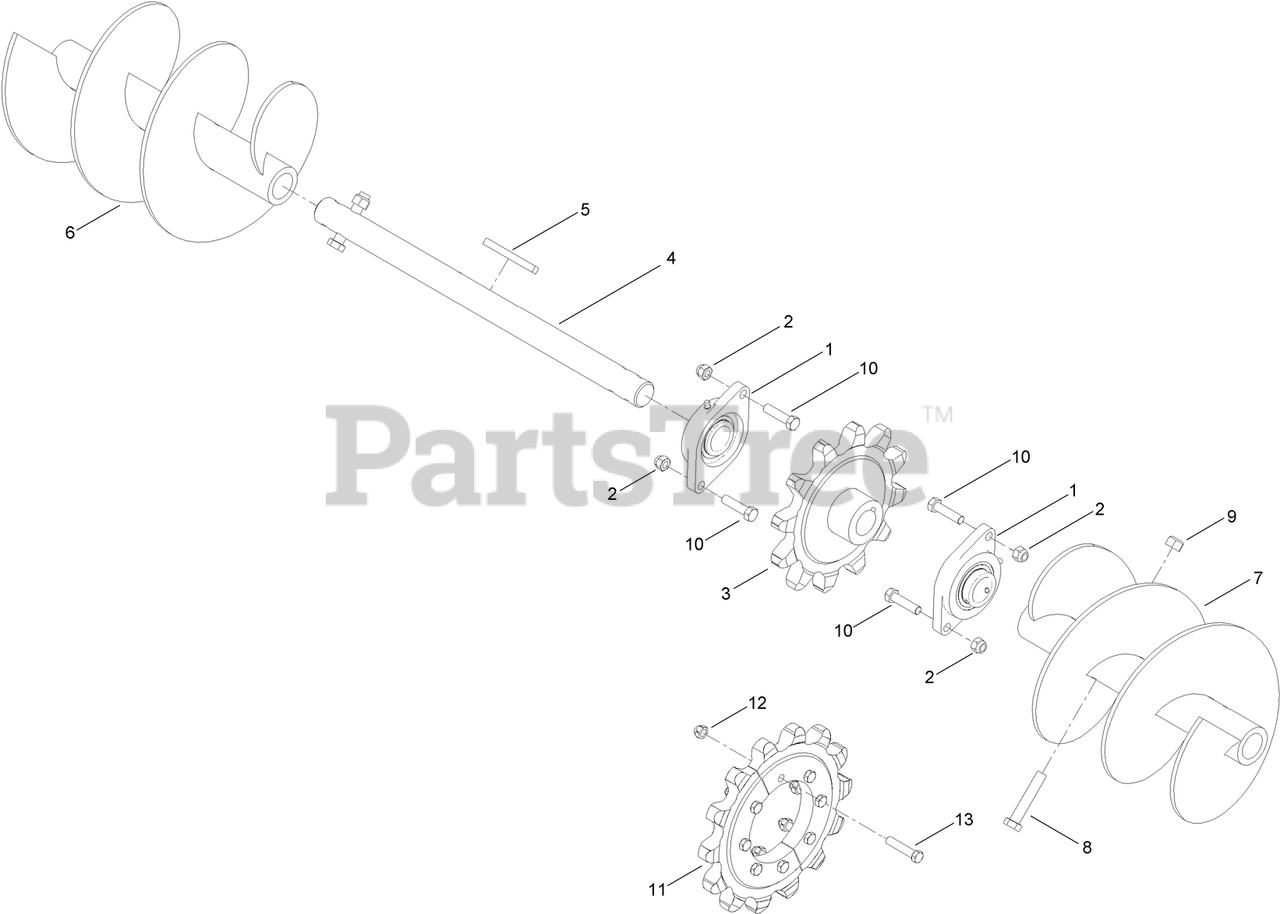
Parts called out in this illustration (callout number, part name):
1	BEARING-BALL, 2-BOLT FLANGE (2 IN)
2	NUT-LOCK, HEX
3	SPROCKET-12T
4	SHAFT-AUGER
5	KEY-SQUARE
9	NUT-LOCK
10	SCREW-HH
11	SPROCKET-SPLIT, 14T
12	NUT-HEX
13	SCREW-HH
